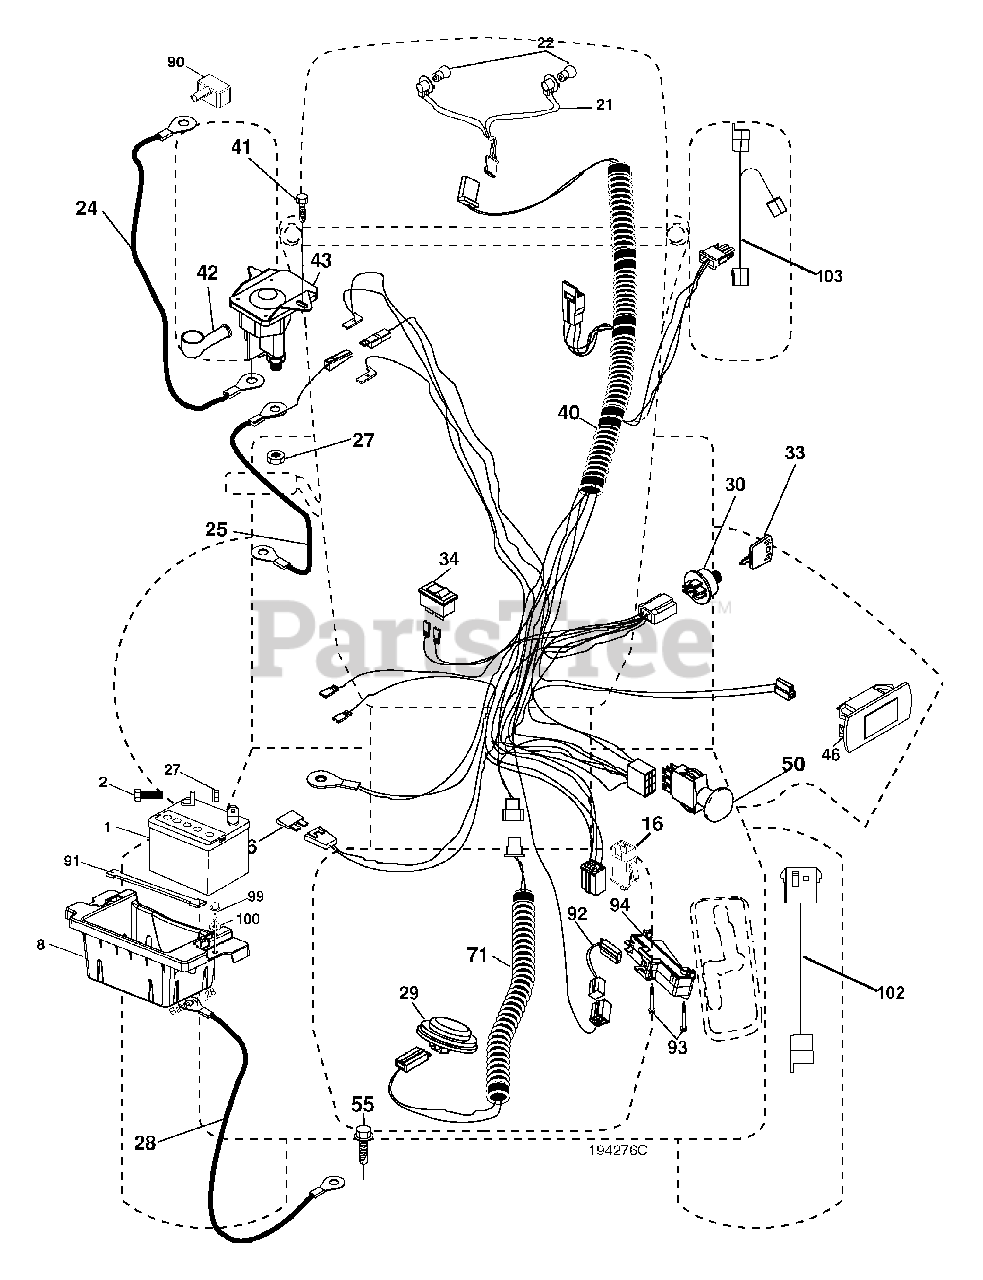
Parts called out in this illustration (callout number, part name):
1	Battery
2	Bolt Hex Hd 1/4-20 unc x 3/4
8	Battery Box
16	Switch Interlock
21	Harness Socket Light
22	Bulb, Light # 1156
24	Cable Battery
25	Cable Starter
27	Nut Keps Hex 1/4-20 unc
28	Cable Ground 21 Blk 6 Ga.
29	Switch Seat
30	Switch Ign
33	Key Ign Molded Generic
34	Switch Light/Reset
40	Harness Ign. Dash
41	Screw Thd Cut 1/4-20 x 1/2
42	Cover Terminal Red
43	Solenoid
46	Gauge Hourmeter
50	Switch PTO
55	Screw Thdrol 5/16-18 x 3/4
59	Outlet 12-Volt
71	Harness Chassis
90	Cover Terminal Battery
91	Strap Battery
92	Harness Pigtail Console ROS
93	Screw Plastite 10-14 x 2.0
94	Module Reverse ROS
99	Screw Hexwsh Thdrol 1/4-20 x 3/4
100	Washer 9/32 x 7/8 x 16 Ga.
102	Pigtail MATNLK Harness
103	Harness Pigtail 12v Outlet
